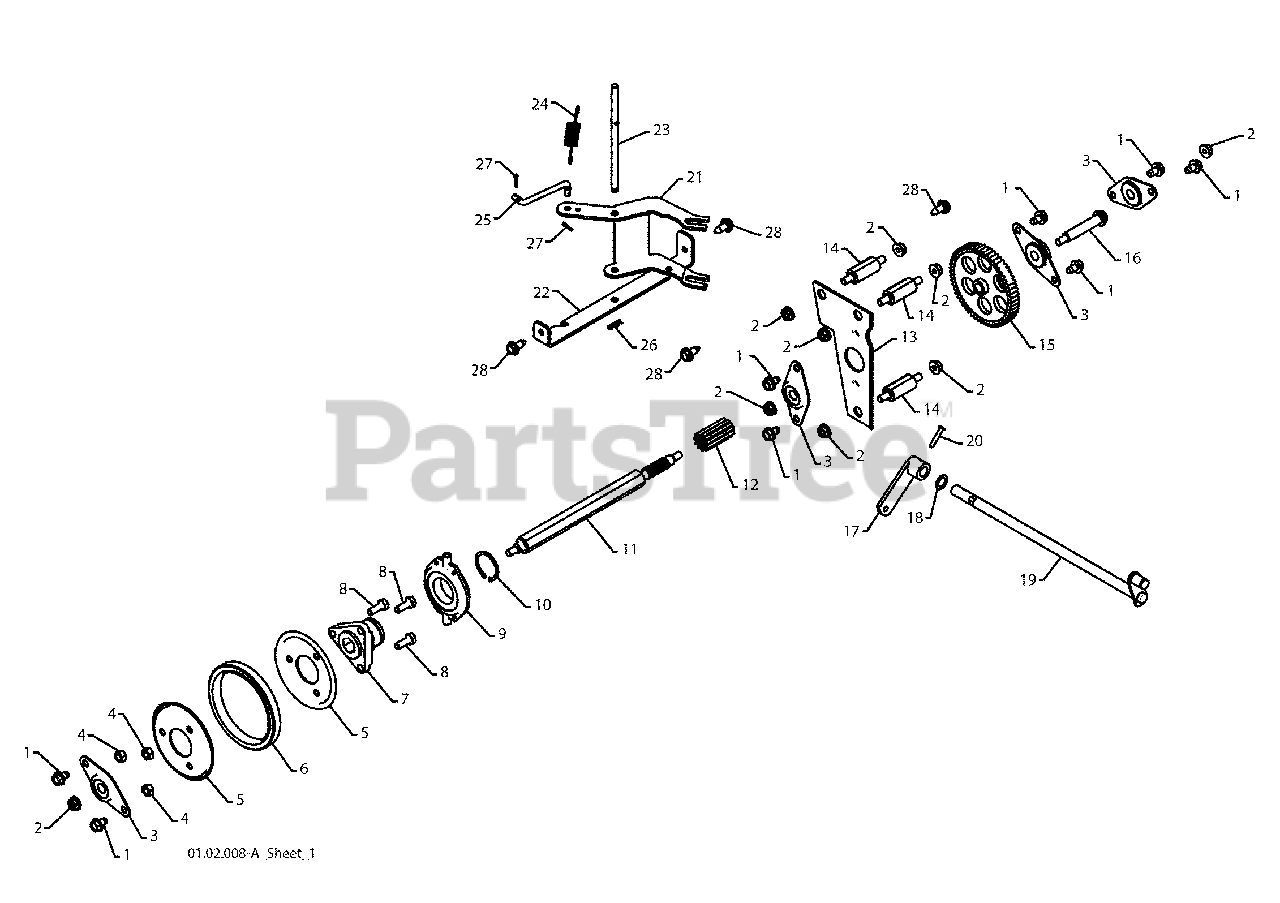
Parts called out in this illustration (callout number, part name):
1	BOLT 5/16--18 X .500
2	NUT 5/16--18
3	FLANGE BEARING
4	NUT 5/16--18
5	RUBBER WHEEL PLATE
6	RUBBER WHEEL RING
7	RUBBER WHEEL HUB
8	BOLT 5/16--18 X .875
9	TRUNNION BEARING ASSEMBLY
10	RETAINER
12	PINION GEAR
13	AUXILIARY PLATE
14	SPACER PLATE
15	INTERMEDIATE GEAR
16	AUXILIARY SHAFT
17	CONTROL ARM
19	CONTROL SHAFT ASSEMBLY
20	CLEVIS PIN
21	SHIFTER LEVER
22	PIVOT BRACKET
25	SHIFTER LINK
28	BOLT 5/16--18 x .750
